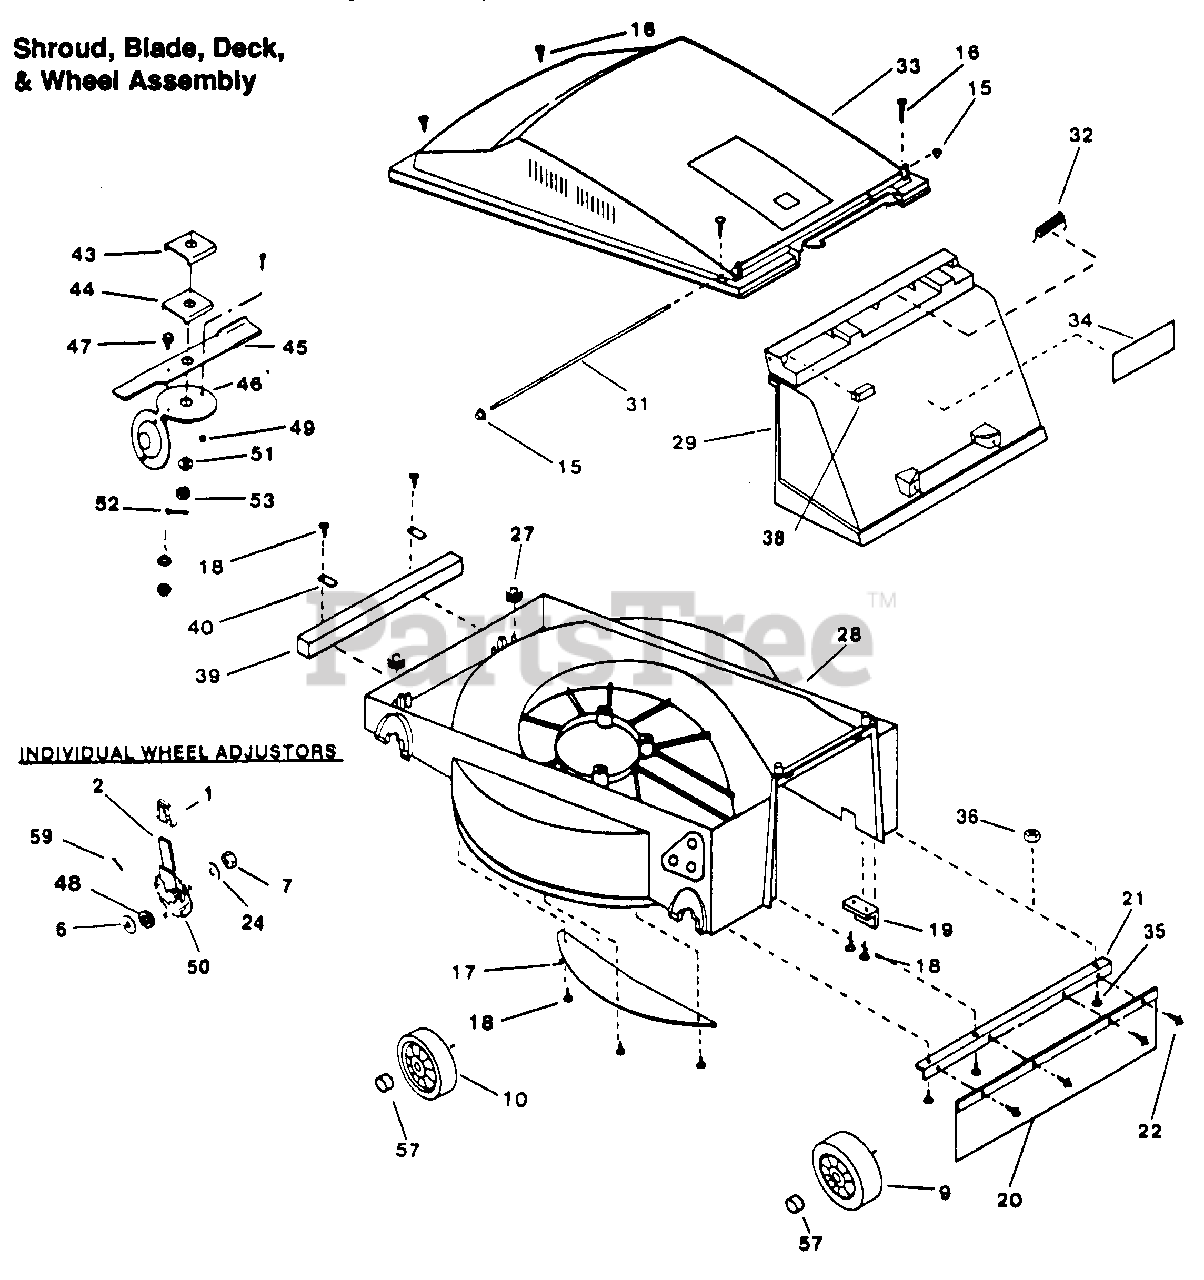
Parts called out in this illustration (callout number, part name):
2	Handle-Wheel Adjust
6	Flat Washer 1/2"
7	Nut 3/8-16 Locking
9	8" Wheel
10	7" Wheel
15	Retainer
16	Screw #10-16 x 1"
17	Cover Plate
18	Screw #10-16 x 3/4"
19	Retainer-Axle
20	Trail Shield
21	Hanger
22	Blind Rivet
24	Flat Washer 3/8"
27	Fastener-Shroud
31	Pin-Rear Door
32	Spring-Rear Door
33	Shroud-Motor
34	Decal-Data & Warning
35	Screw #10-24 x 3/4"
36	Nut #10-24
38	Block-Rear Door
39	Counterweight
40	Retainer
43	Blade Adaptor
44	Adaptor Insulator
45	Blade-20"
46	Blade Insulator
47	Carriage Bolt 5/16-18 x 3/4" (Short Sq.-Neck)
48	Plastic Wheel Spacer
49	Keps Nut 5/16-18
50	Adjuster
51	Washer
52	Cotter Pin 3/32 x 1 " (Stainless Steel)
53	Blade Nut
57	Hub Cap
59	Cotter Pin 3/32 x 3/4"
